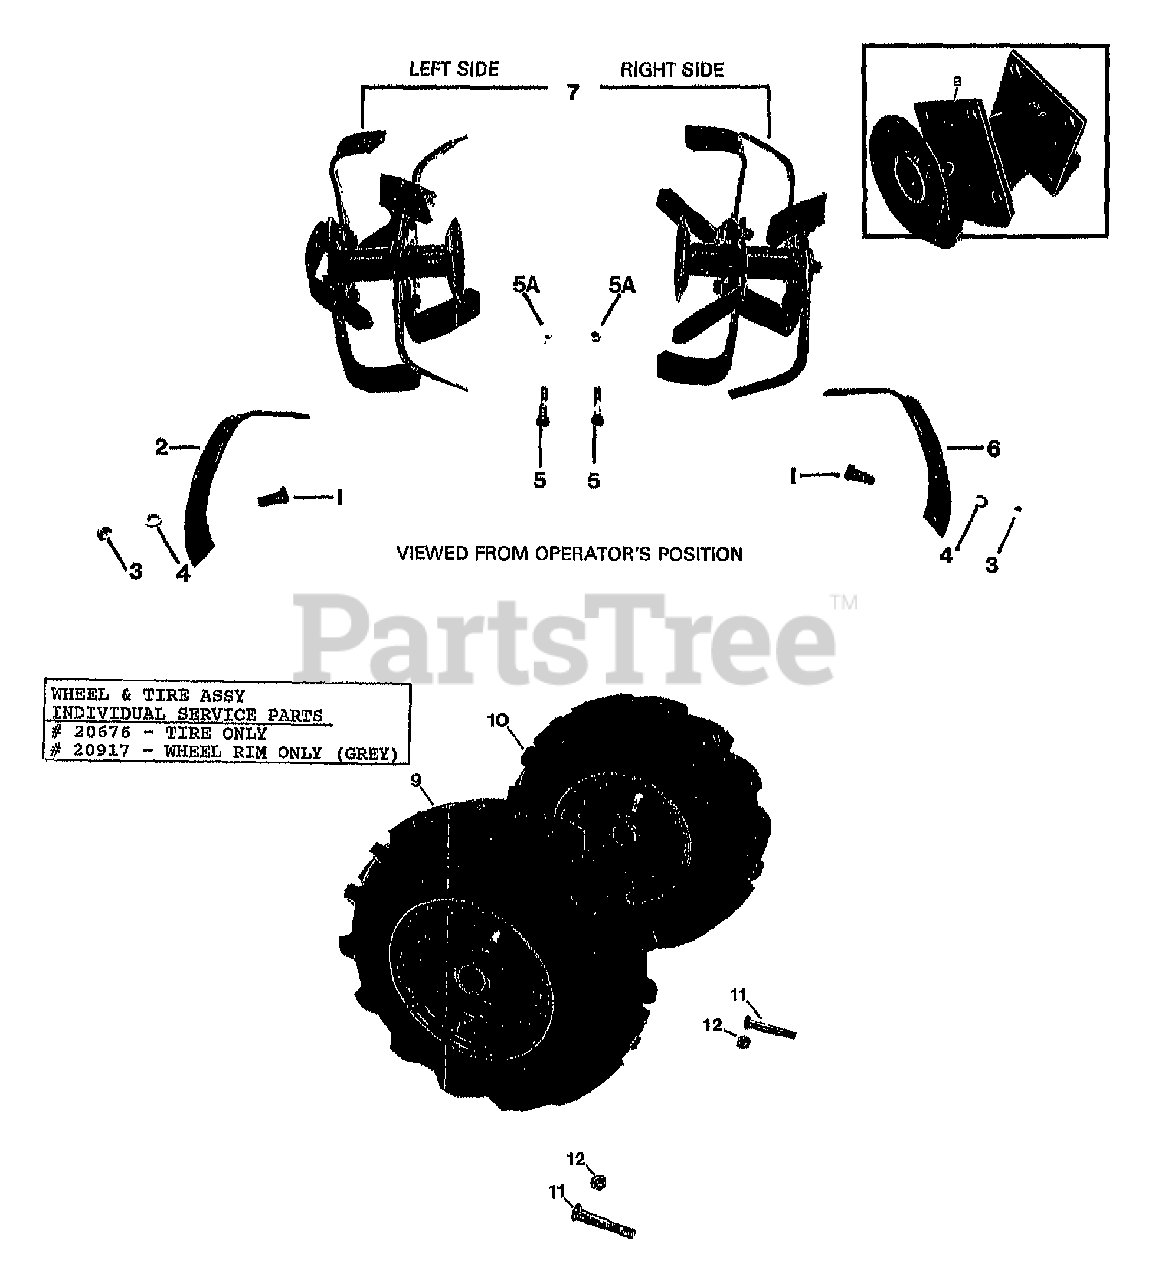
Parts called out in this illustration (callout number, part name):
1	SCR-HH 3/8-16X1.0 G5 ZP
2	TINE-BOLO RT W/HDW
3	NUT-HEX 3/8-16 ZP
4	WASHER-LK .375 @ DEPL
5	SCR-HH 3/8-16X2.00 G8 (HOLDER TO TILLER SHAFT)
5A	NUT-H/LK 3/8-16
6	TINE-BOLO LT W/HDW
7	P-1 BOLO&HOLDS
8	T HOLDER
9	ASSM-TIRE LT 4.10 X 6" (10-20LBS. AIR REQ)
10	ASSM-TIRE RT 4.10 X 6"
11	BOLT-HH 5/16-18 X 2 G5 ZP
12	NUT-H/LK 5/16-18
